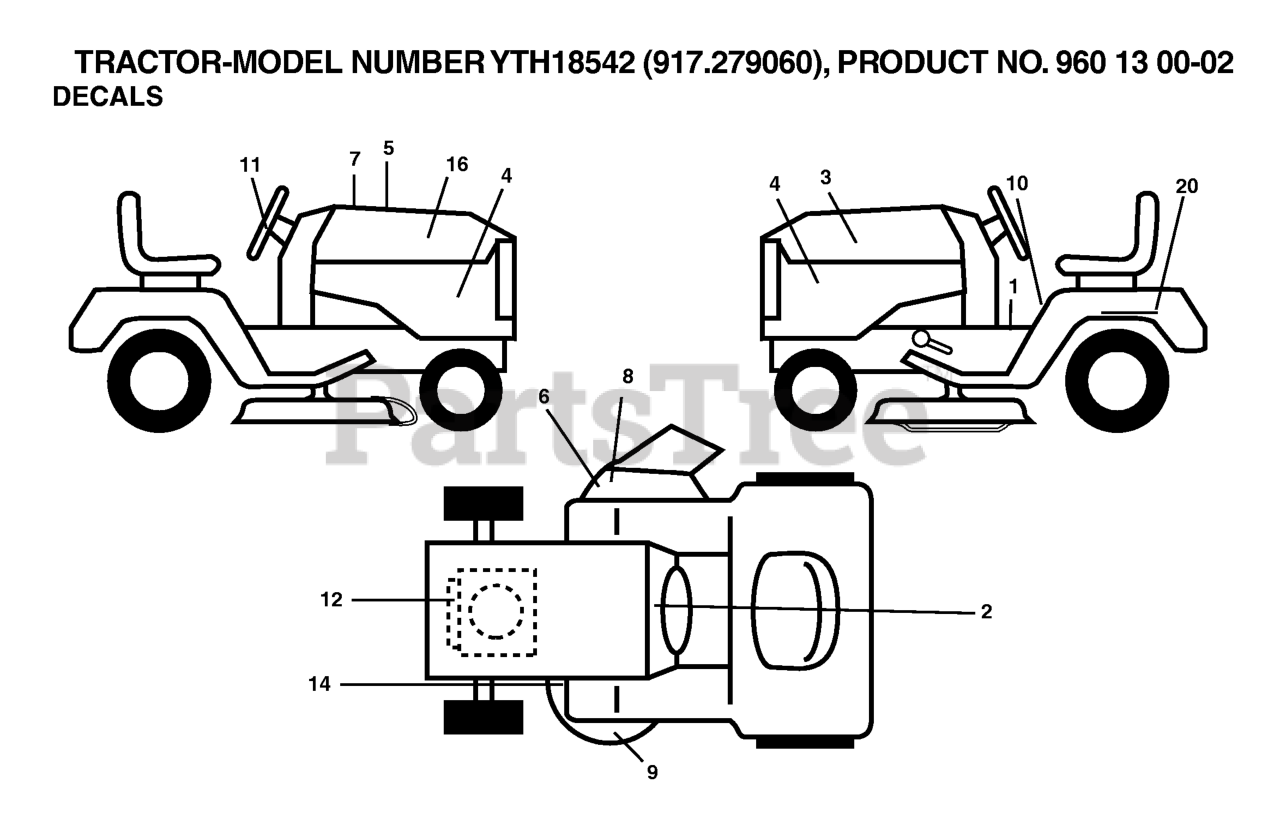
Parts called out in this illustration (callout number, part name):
4	DECAL, YTH18542
5	DECAL HOOD CUST. RESP.
6	DECAL.WARN.KEEP.HAND.AWAY
7	DECAL, LTH184
8	DECAL DECK "B" 42"
10	DECAL FENDER DANGER
11	DECAL.STEERING.HUSQ.BLUE
14	DECAL V BELT SCHEMATIC
20	DECAL BTRY SYMBOLS
